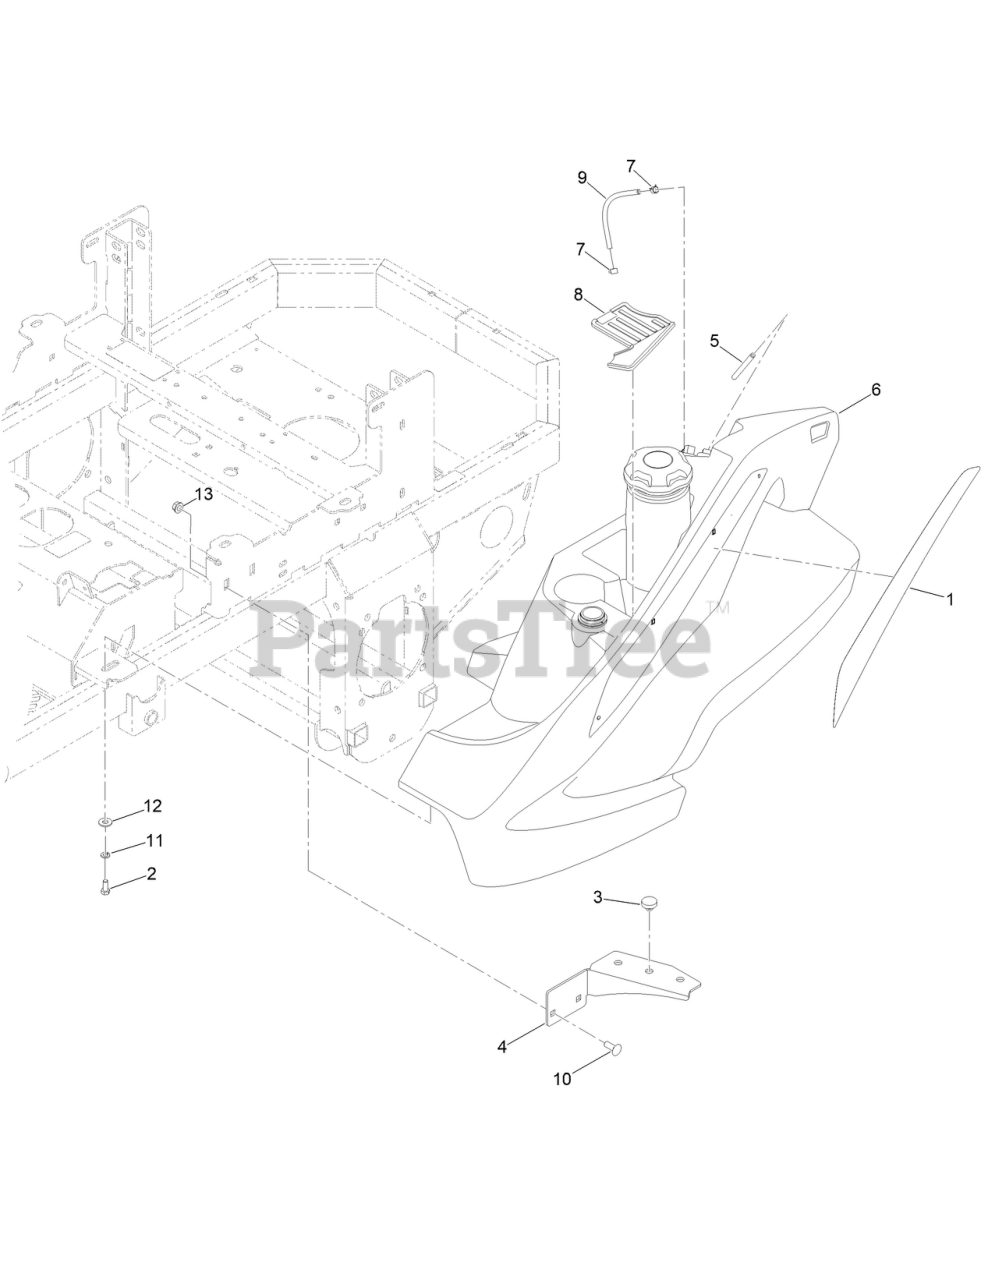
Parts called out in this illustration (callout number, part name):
1	DECAL-POD LH
2	SCREW-HH
3	PUSH-IN RUBBER BUMPER MWR FLOOR
4	RT/SRT GAS TANK SUPPORT BKT
5	MWR FUEL TANK BLACK 3/16IN VENT TUBE 1FT
6	MWR GASOLINE FUEL TANK ASSY
7	1/2IN (#8) HOSE CLAMP
8	RUBBER TANK STORAGE COMPARTMENT INSERT
9	1/4IN SAE J30R7 BULK HOSE 1FT
10	3/8-16 X 1 CARRIAGE BOLT YZ GR.8
11	WASHER-LOCK
12	WASHER-FLAT
13	3/8-16 HEX FLANGE NUT W/SERR ZINC YELLOW
